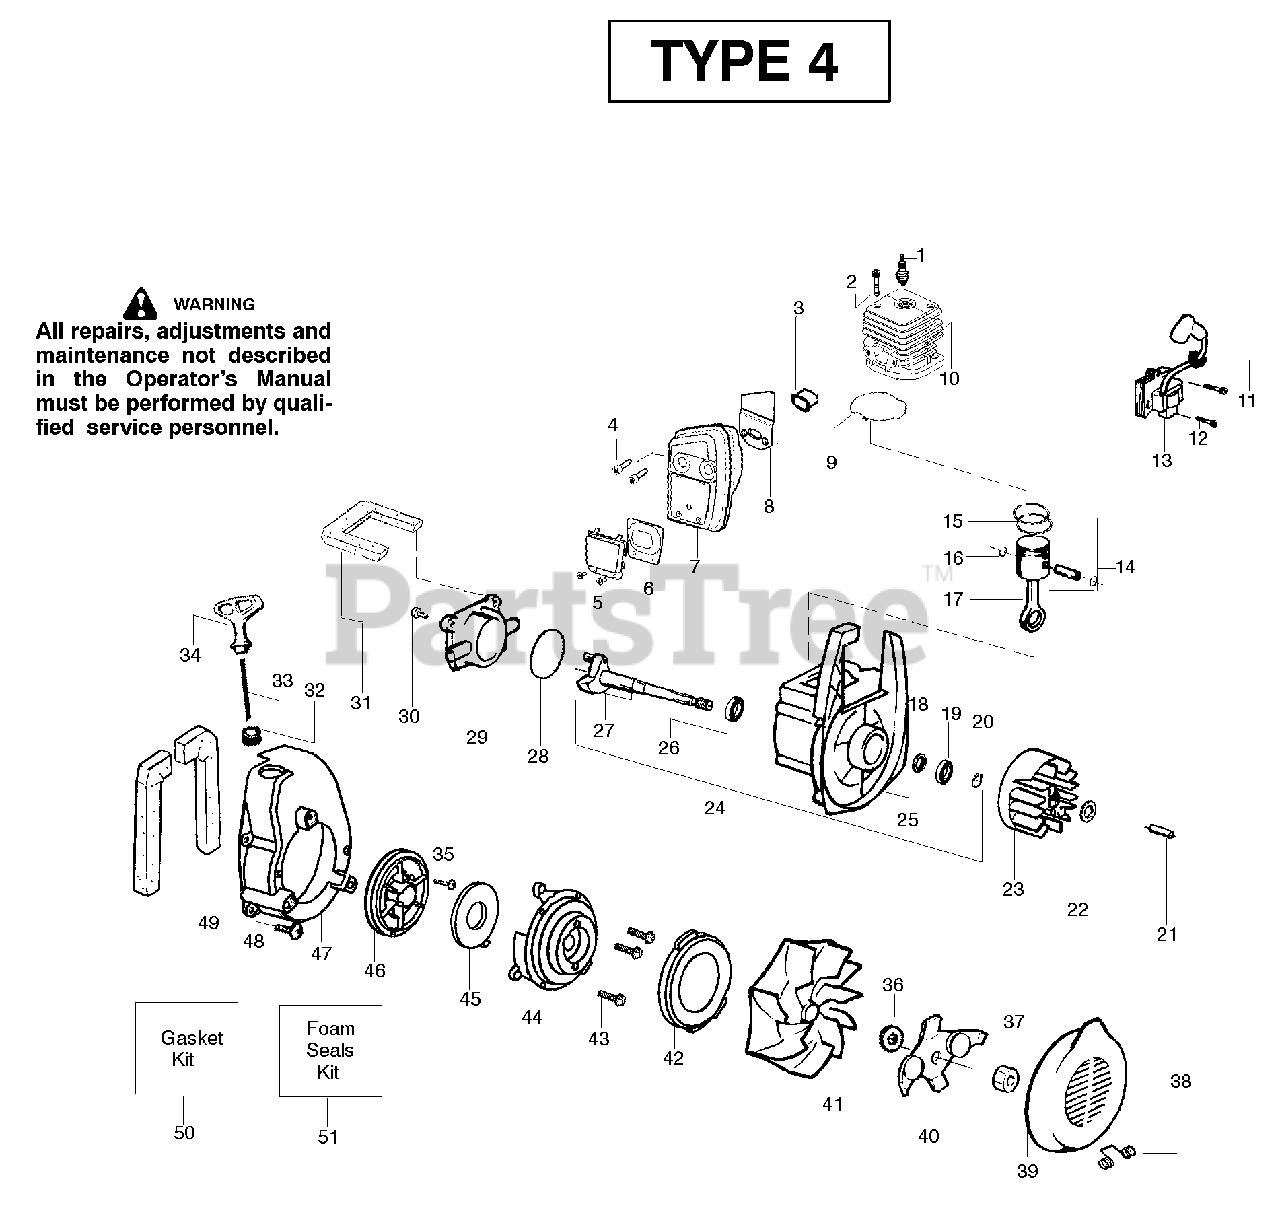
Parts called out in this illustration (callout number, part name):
1	Spark Plug (RCJ-6Y)
3	Insulator-Heat
4	Screw-Muffler-Internal
6	Kit-Spark Screen
7	Kit-Muffler
8	Gasket-Baffle (kit)
9	Gasket-Cylinder (kit)
10	Kit-Cylinder
11	Grommet-Ign. Module
12	Screw-Ignition Module
13	Ignition Module
14	Kit-Piston
15	Piston Ring
16	Retainer-Piston Pin
17	Assy-Connecting Rod
18	Seal-Crankcase
19	Bearing-Outer
20	Retainer Ring-C'chaft
21	Spacer-Flywheel
23	Assy-Flywheel
24	Assy-Crankcase/Crank shaft
25	Assy-Crankcase
26	Bearing-Inner
27	Assy-Crankshaft
28	O-ring-C/case (kit)
29	Cover-Crankcase
30	Screw
31	Foam-219mm (kit)
32	Eyelet-Flange
33	Kit-Rope
34	Handle-Starter
35	Screw-Rope
36	Washer-Belleville
38	Spring-Return Cover
39	Inlet Door
40	Assy-Mulch Blade
41	Assy-Impeller
42	Seal-Ring
44	Housing-Pulley
45	Spring-Starter
46	Kit-Starter Pulley
47	Fan Housing
48	Screw
49	Foam-182mm (kit)
50	Kit-Gasket
51	Kit-Foam Seals
